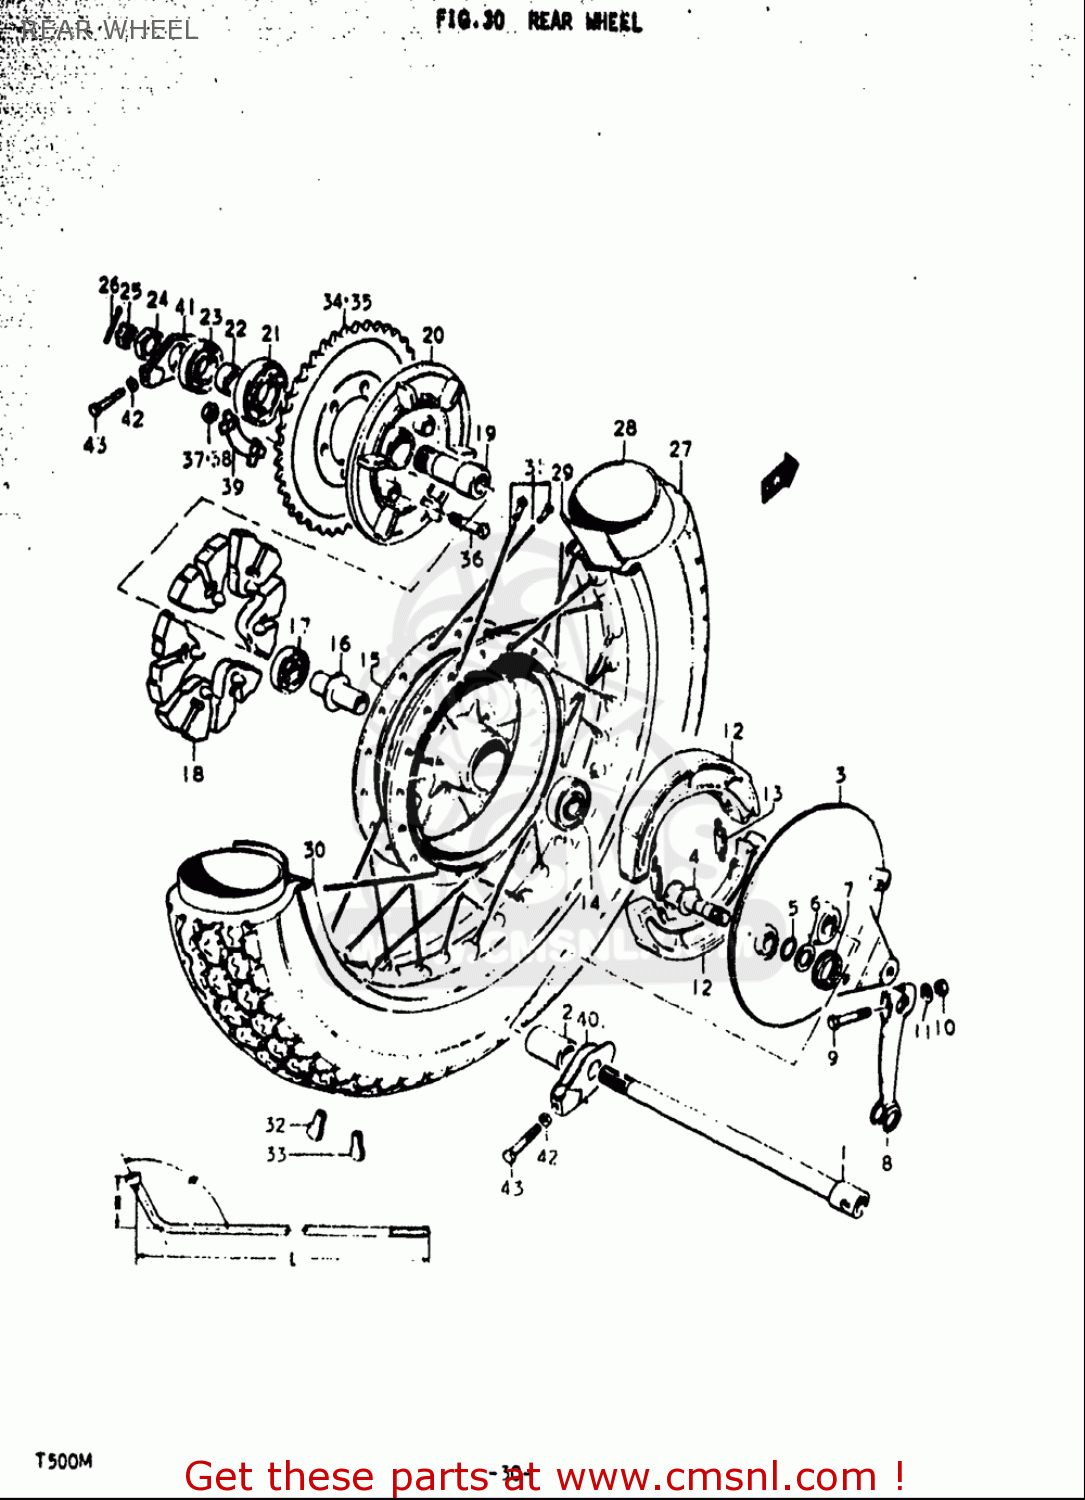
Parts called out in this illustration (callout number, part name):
1	AXLE,REAR
4	CAM,RR BRAKE
5	O RING(D:2.4,ID:14.8)
6	WASHER(15.5X24X1.6)
7	SPRING
9	BOLT
10	NUT
11	WASHER
12	SHOE SET,BRAKE (NAS)
13	SPRING,BRAKE SHOE
14	BEARING
16	SPACER
17	BEARING(17X40X12)
18	ABSORBER,RR HUB SHOCK
21	BEARING(25X52X15)
22	SPACER (25X30.5X11.3)
23	SEAL,OIL(30.5X52X8)
24	NUT
25	NUT 16MM
26	PIN, COTTER
28	TUBE,INNER
29	PROTECTOR,INNER TUBE
30	RIM,WHEEL
31	SPOKE SET,RR WHEEL
32	BALANCER,WHEEL (B)
33	BALANCER,WHEEL (30G)
36	BOLT(10X35.5)
38	NUT
39	WASHER
41	ADJUSTER,CHAIN,L
42	NUT
43	BOLT(8X50)
